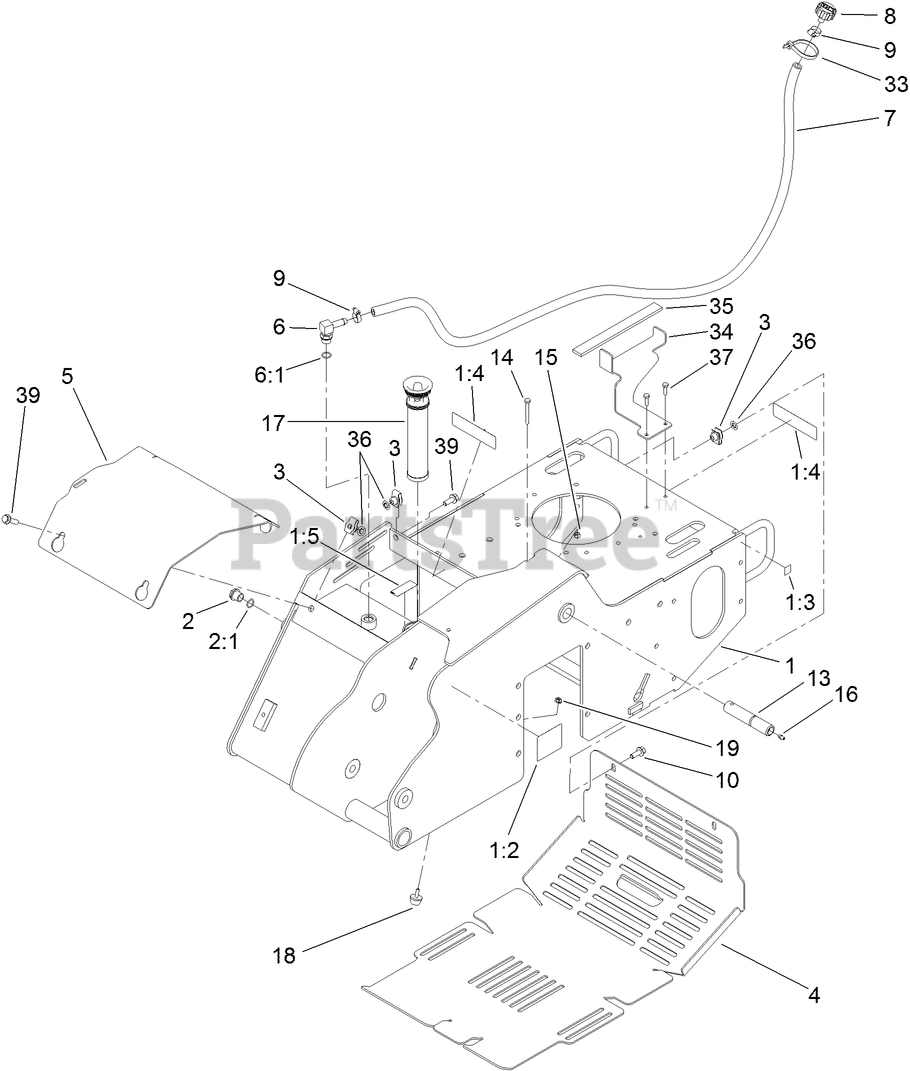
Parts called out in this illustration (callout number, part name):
1	MAIN FRAME ASM
1:2	DECAL-WARNING
1:3	DECAL-POINT, LIFT
1:4	DECAL-DANGER
1:5	DECAL-OIL, HYD
2	SIGHT GLASS ASM
2:1	O-RING
3	NUT-CLIP, U
4	COVER-REAR
5	PLATE-COVER, FRONT
6	FITTING-ELB 90
6:1	O-RING
7	HOSE-BREATHER
8	BREATHER
9	CLAMP-HOSE
10	SCREW-HHF
13	PIN-PIVOT
14	SCREW-HH
15	NUT-LOCK, NI
16	FITTING-GREASE
17	IN-TANK FILTER ASM
18	BUMPER
19	NUT-HF
33	TIE-CABLE
34	BRACKET-TANK
35	PAD-FOAM
36	NUT-PUSH
37	SCREW-HH
39	SCREW-HHF
